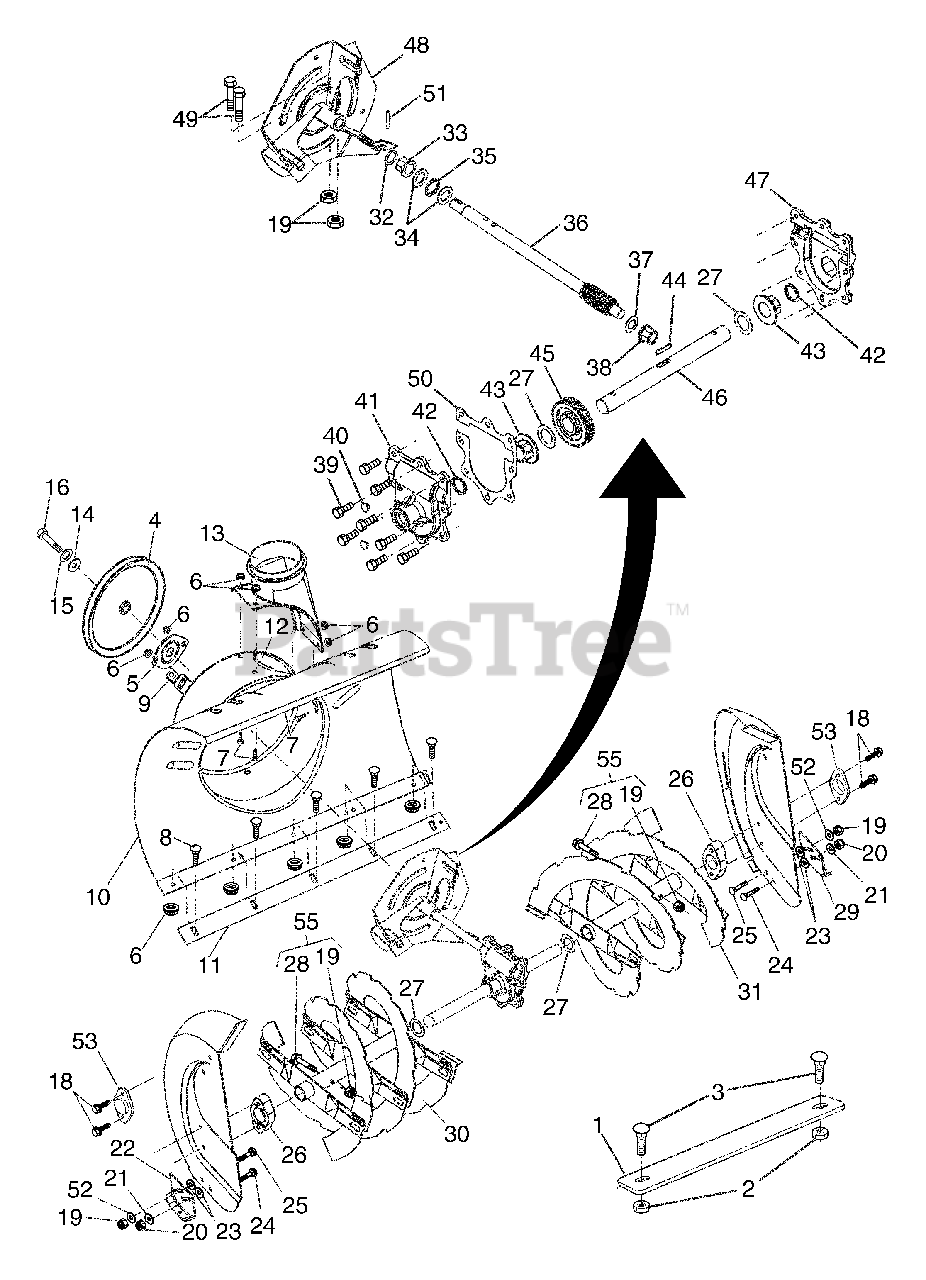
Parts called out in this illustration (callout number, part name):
1	Bar, Weight
2	Nut, Hex 5/16-18
3	Bolt, Carriage 5/16-18 x 1-1/4
4	Pulley, Impeller
5	Bearing Assembly, Flange
6	Nut, Hex Flange 5/16-18
7	Bolt, Flat Head, Carriage 5/16-18 x 5/8
8	Bolt, Carriage 5/16-18 x 5/8
9	Nut, Cage 3/8-16
10	Housing, Auger
11	Bar, Scraper
12	Bracket, Corner Discharge
13	Base, Discharge Chute
14	Washer, Flat
15	Washer, Lock 5/16
16	Screw, Hex Head 5/16-18 x 3/4
18	Screw, Hex Head 5/16 x 1
19	Nut, Hex Lock 1/4-20
20	Nut, Hex Lock 5/16-18
21	Washer, Flat
22	Skid Plate, RH
23	Washer, Nylon, Friction
24	Bolt, Carriage 5/16-18 x 3/4
25	Bolt, Shoulder
26	Bearing Retainer, Plastic
27	Washer, Thrust, 1"
28	Bolt, Shear
29	Skid Plate, LH
30	Auger Assembly, RH
31	Auger Assembly, LH
33	Bushing, Flange 3/4
34	Washer, Thrust 3/4
35	Bearing, Thrust 3/4
36	Shaft, Impeller
37	Washer, Thrust 5/8
38	Bushing, Flange 5/8
39	Screw, Hex Head 5/16-18 x 3/4
40	Plug, Case
41	Housing, Gearbox, RH
43	Bushing, Flange, 1"
44	Key, Square 1/4 x 1/4 x 7/8
45	Gear, Worm
46	Shaft, Auger
47	Housing, Gearbox, LH
48	Impeller Assembly
49	Screw, Hex Head 1/4-20 x 1-5/8
50	Gasket, Gearbox
51	Pin, Roll 3/16 x 1-1/8
52	Washer, Flat
53	Bearing, Auger
55	Kit, Shear
